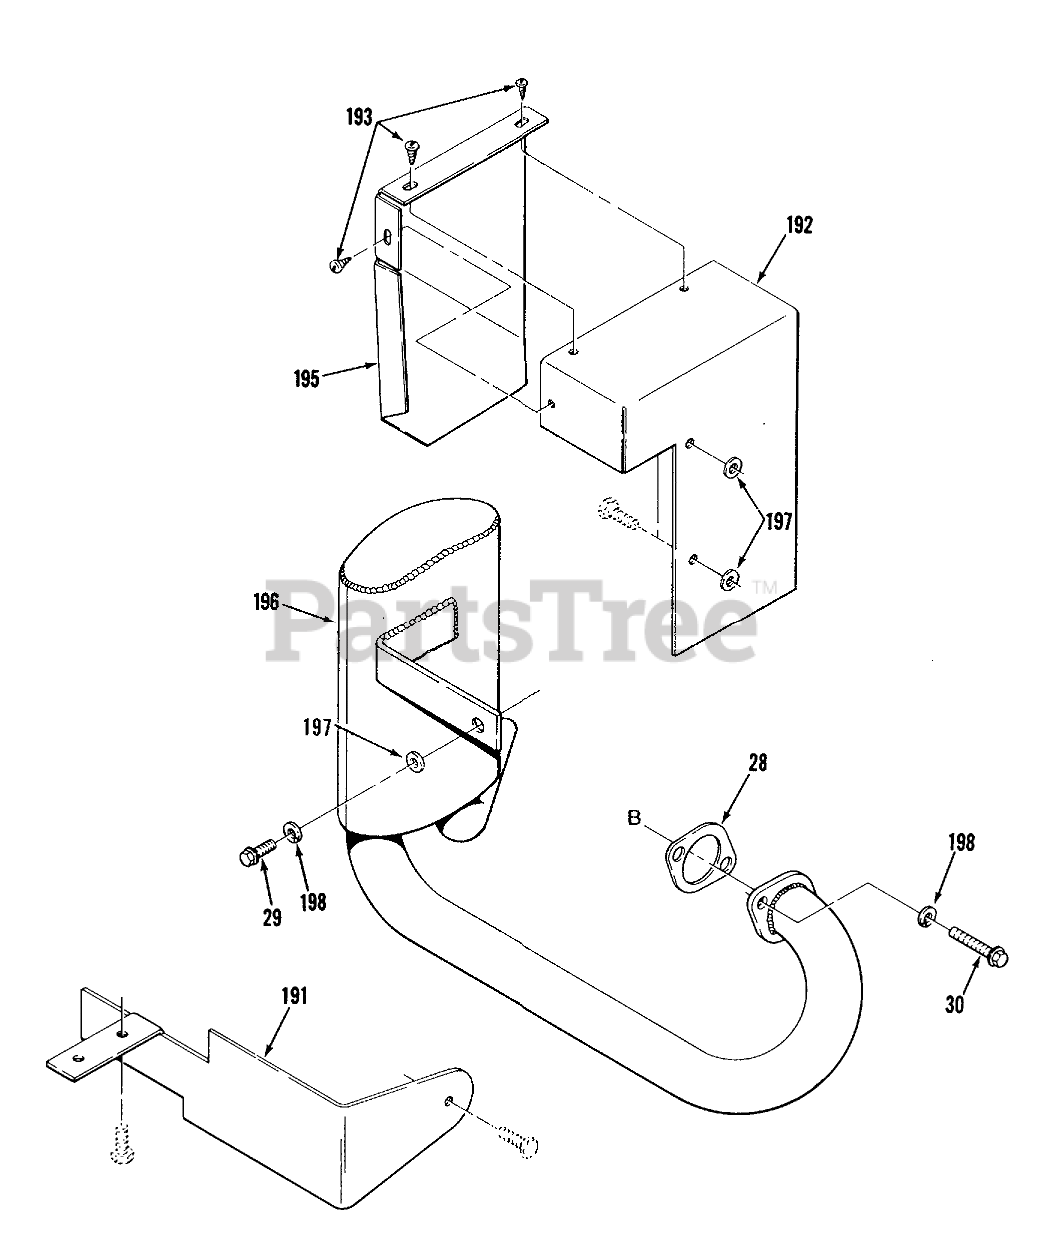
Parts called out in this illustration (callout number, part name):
28	GASKET-EXH FC-290V
29	Bolt-Flanged (8X12)
30	Bolt-Flanged (8X45)
191	DEFLECTOR-FRONT B
192	SHIELD-HEAT B
193	SCRW-HX S.T.#8 X 3/8
195	SHIELD-HEAT
196	Muffler-Black
197	WASHER 5/16 SAE
198	Lockwasher
